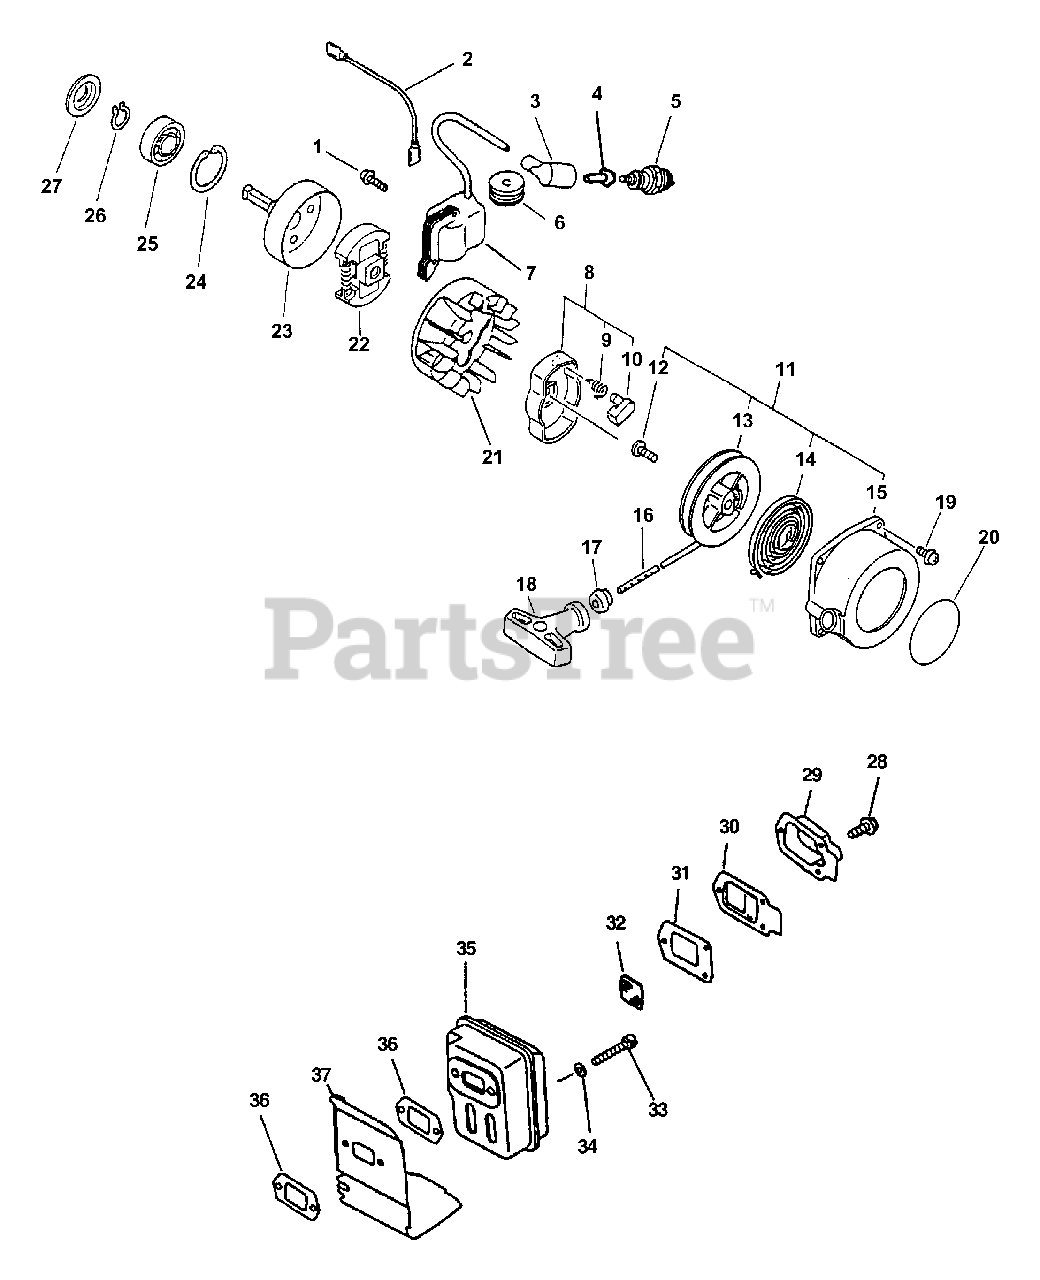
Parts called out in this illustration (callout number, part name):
1	SCREW 4×22
2	LEAD
3	CAP, SPARK PLUG
4	TERMINAL, SPARK PLUG
5	SPARK PLUG - BPM7A
5	SPARK PLUG - BPMR7A
7	COIL, IGNITION
8	PAWL ASSY, STARTER
9	SPRING, RETURN
10	PAWL, STARTER - BLACK
11	STARTER ASSY, RECOIL
12	SCREW
13	REEL, ROPE
14	SPRING, RECOIL
15	CASE, RECOIL STARTER
17	GUIDE, ROPE
18	GRIP, STARTER
19	BOLT 4×16
20	LABEL, ECHO
21	FLYWHEEL
22	CLUTCH ASSY
23	DRUM, CLUTCH
24	RING, SNAP Ø32
25	BEARING, BALL 6201-ZZ
26	RING, RETAINING - 12
27	STOPPER, PIPE
28	SCREW 4×10
29	GUIDE, EXHAUST - INNER
30	GUIDE, EXHAUST
31	GASKET, EXHAUST
32	SCREEN, SPARK ARRESTER
33	BOLT 5×55
34	WASHER, FLAT 5.5×10×0.8
36	GASKET, EXHAUST
37	HEAT SHIELD, EXHAUST
